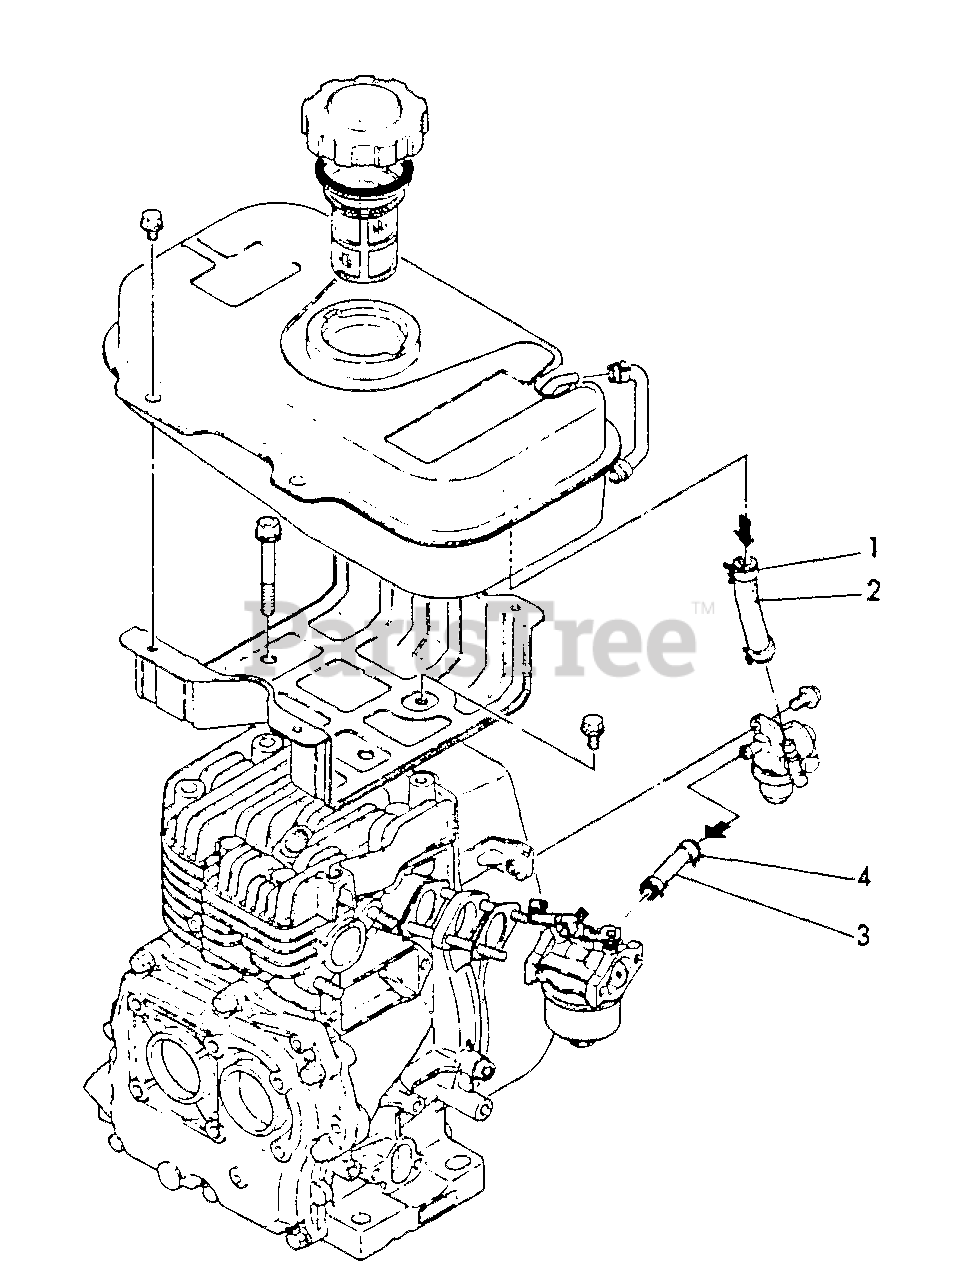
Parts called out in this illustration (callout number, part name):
1	CLAMP, HOSE
2	PIPE - FUEL -- A
3	PIPE - FUEL
4	CLAMP
